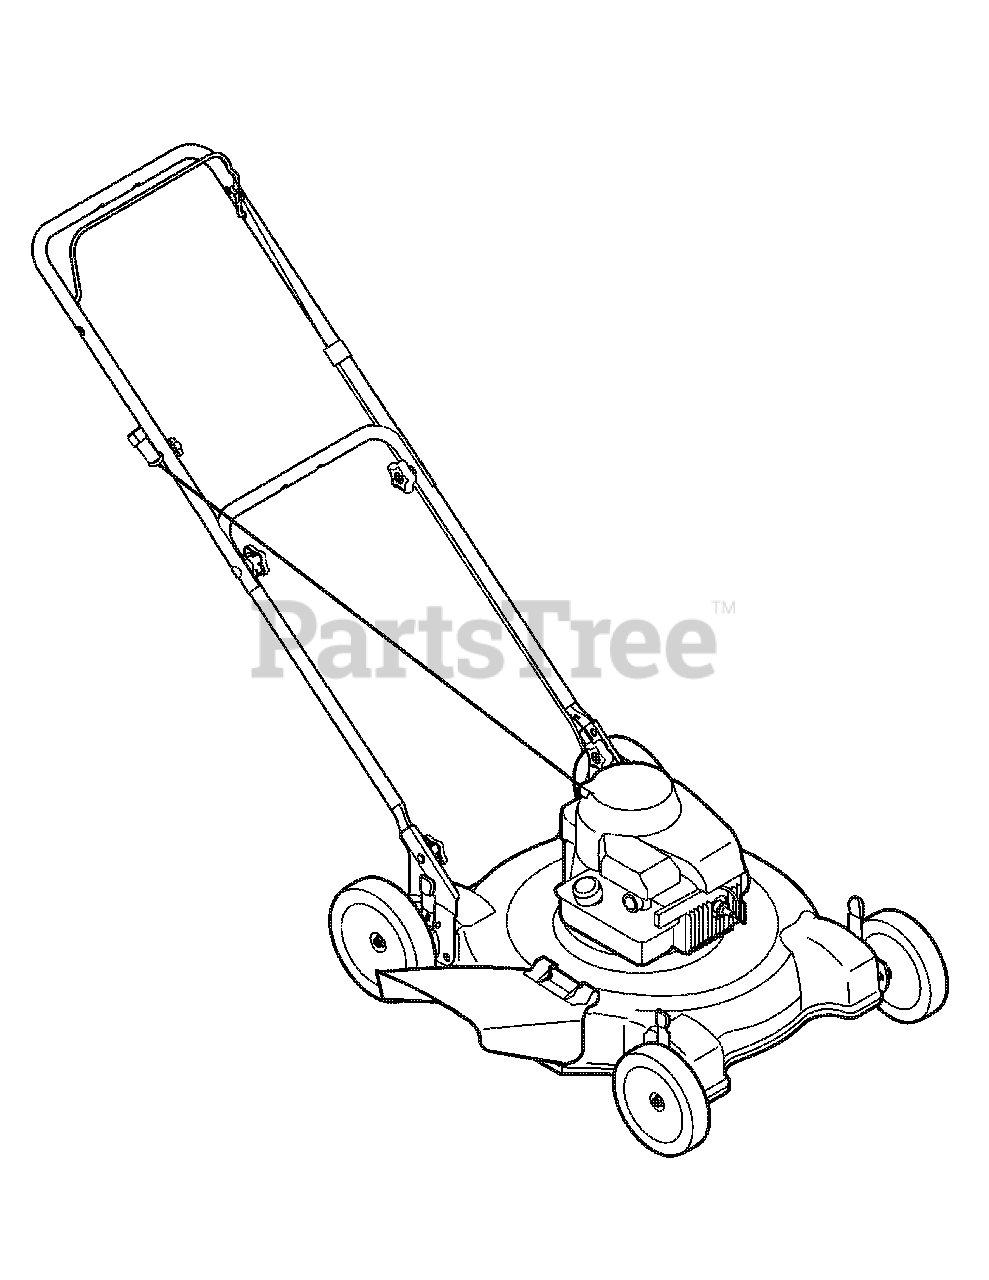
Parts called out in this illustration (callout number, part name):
NA	Pre-Filter
NA	Drive Belt
NA	Drive Cable
NA	Ignition Key
NA	Grass Bag
